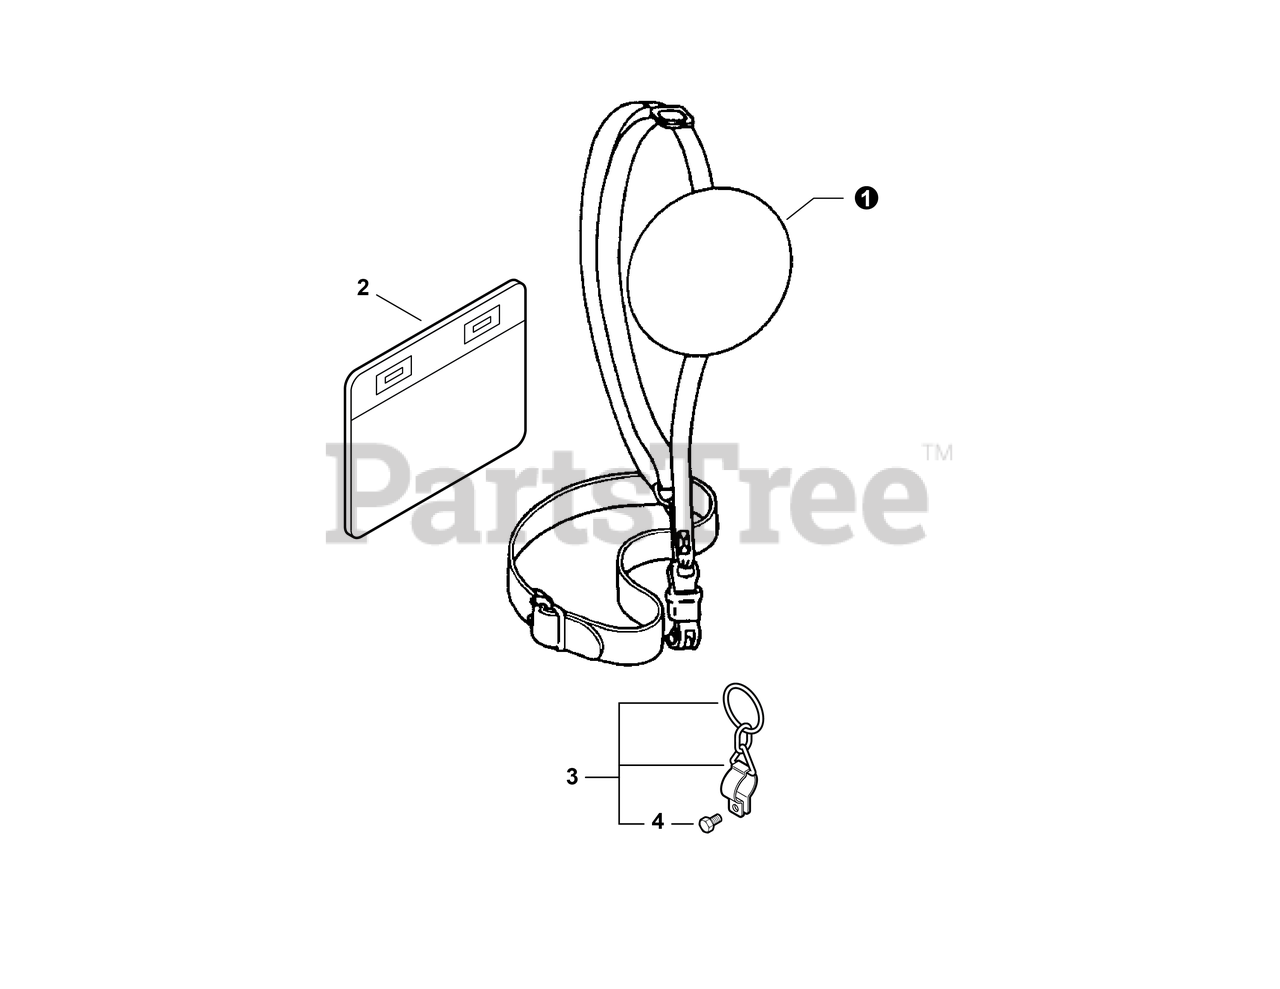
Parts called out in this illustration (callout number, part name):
1	HARNESS, SHOULDER
2	CUSHION
3	HARNESS HANGER KIT
4	BOLT, TORX - 5X12
